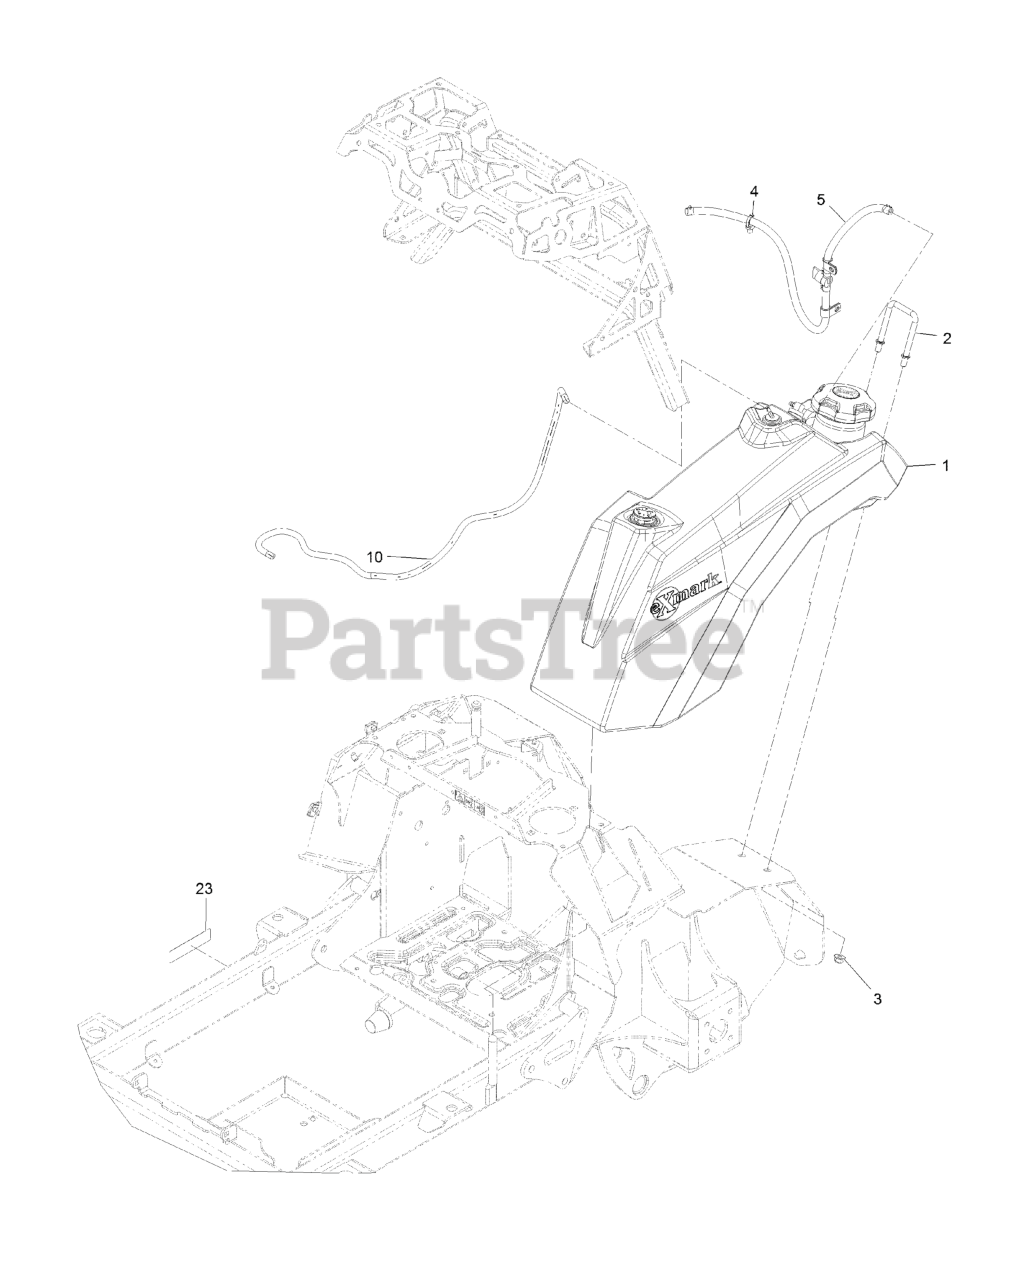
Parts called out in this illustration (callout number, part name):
1	ASSEMBLY, FUEL TANK
2	CLAMP, TANK
3	NUT-HF, NI
4	CLIP-TIE
10	HOSE-FUEL
23	DECAL-ARRESTOR, SPARK
